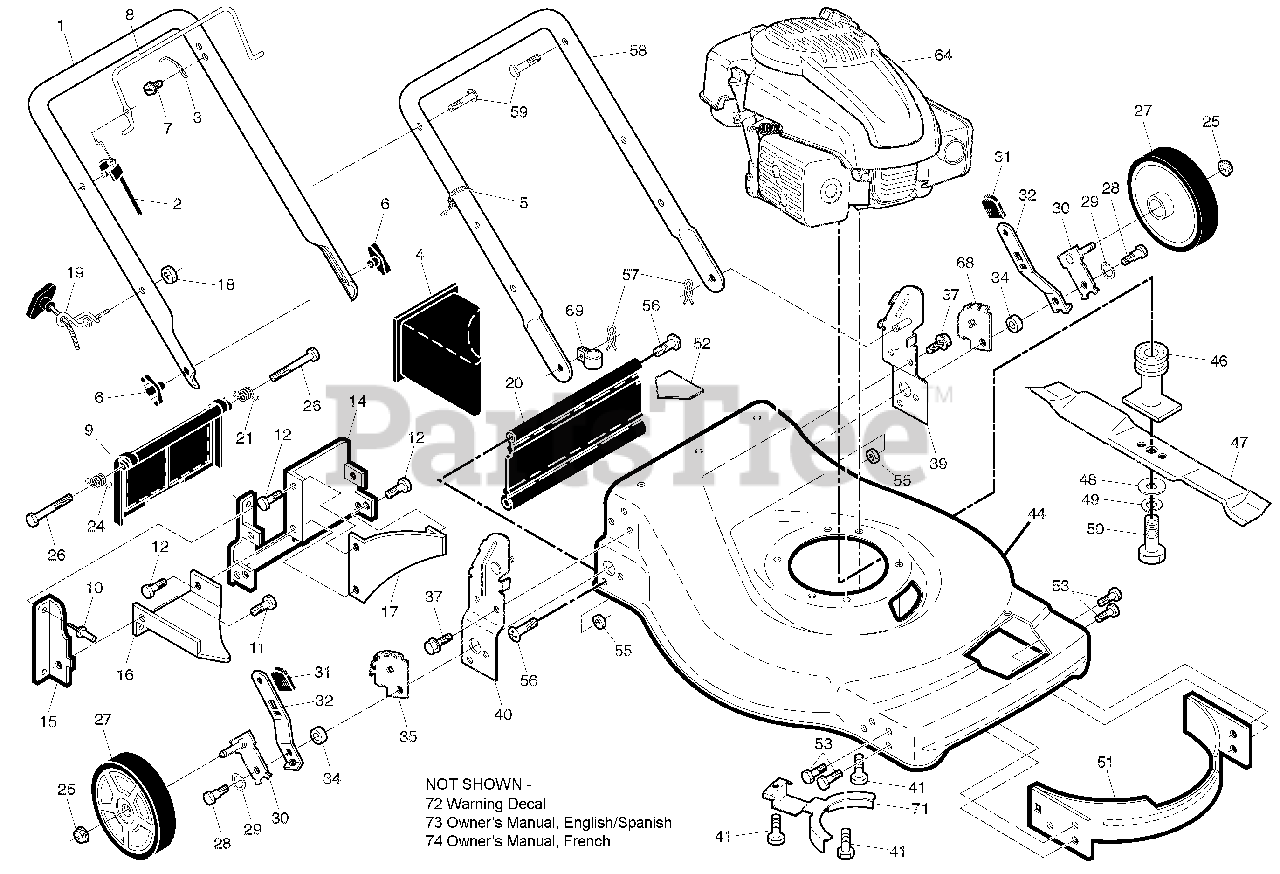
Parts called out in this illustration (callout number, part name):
1	UPPER HANDLE
2	ENGINE CONTROL ZONE CABLE
3	Bracket, Upstop
4	MULCH PLUG
5	Wire Tie
6	KNOB, HANDLE
7	Hex Washer Head Screw
8	CONTROL BAR
9	Rear Door Assembly
10	Pop Rivet
11	Screw, Self-Tapping
12	SCREW, SEMS, HEX HEAD 1/4-20 X
14	Back Plate
15	Side Baffle
16	Discharge Baffle
17	Rear Baffle
18	Lock Nut 1/4-20
19	Rope Guide
20	REAR SKIRT
21	Spring, Rear Door, LH
24	Bolt, Rear Door
25	Nut, Hex
26	Bolt, Rear Door
27	REAR WHEEL
28	Bolt, Shoulder 3/8-16 x 1
29	Washer, Curved, Cylindrical
30	AXLE ARM ASSEMBLY
31	Selector Knob
32	Selector Spring, Front
35	WHEEL ADJUSTING BRKT RH
37	Screw, Sems, Thread Cutting 5/
39	HANDLE BRACKET ASSEMBLY LH
40	HANDLE BRACKET ASSEMBLY RH
41	Screw, Hex Head, Threaded, Rol
44	DECK, WALK BEHIND
46	PULLEY, BLADE ADAPTER
48	Hardened Washer
49	Helical Lockwasher
50	Screw, Hex Head, Grade 8 3/8-2
51	Kit, Front Baffle
52	Danger Decal
53	Screw 1/4-20 x 3/8
55	NUT.CENTERLOCK.3/8-16 UNC.
56	Hinge Screw
57	Hairpin Cotter
58	LOWER HANDLE
59	Handle Bolt
64	Engine, Kohler, Model Number XT800-2013 (For engine service and replacement parts,
68	WHEEL ADJUSTING BRKT LH
69	Clip, Cable
71	BELT KEEPER
